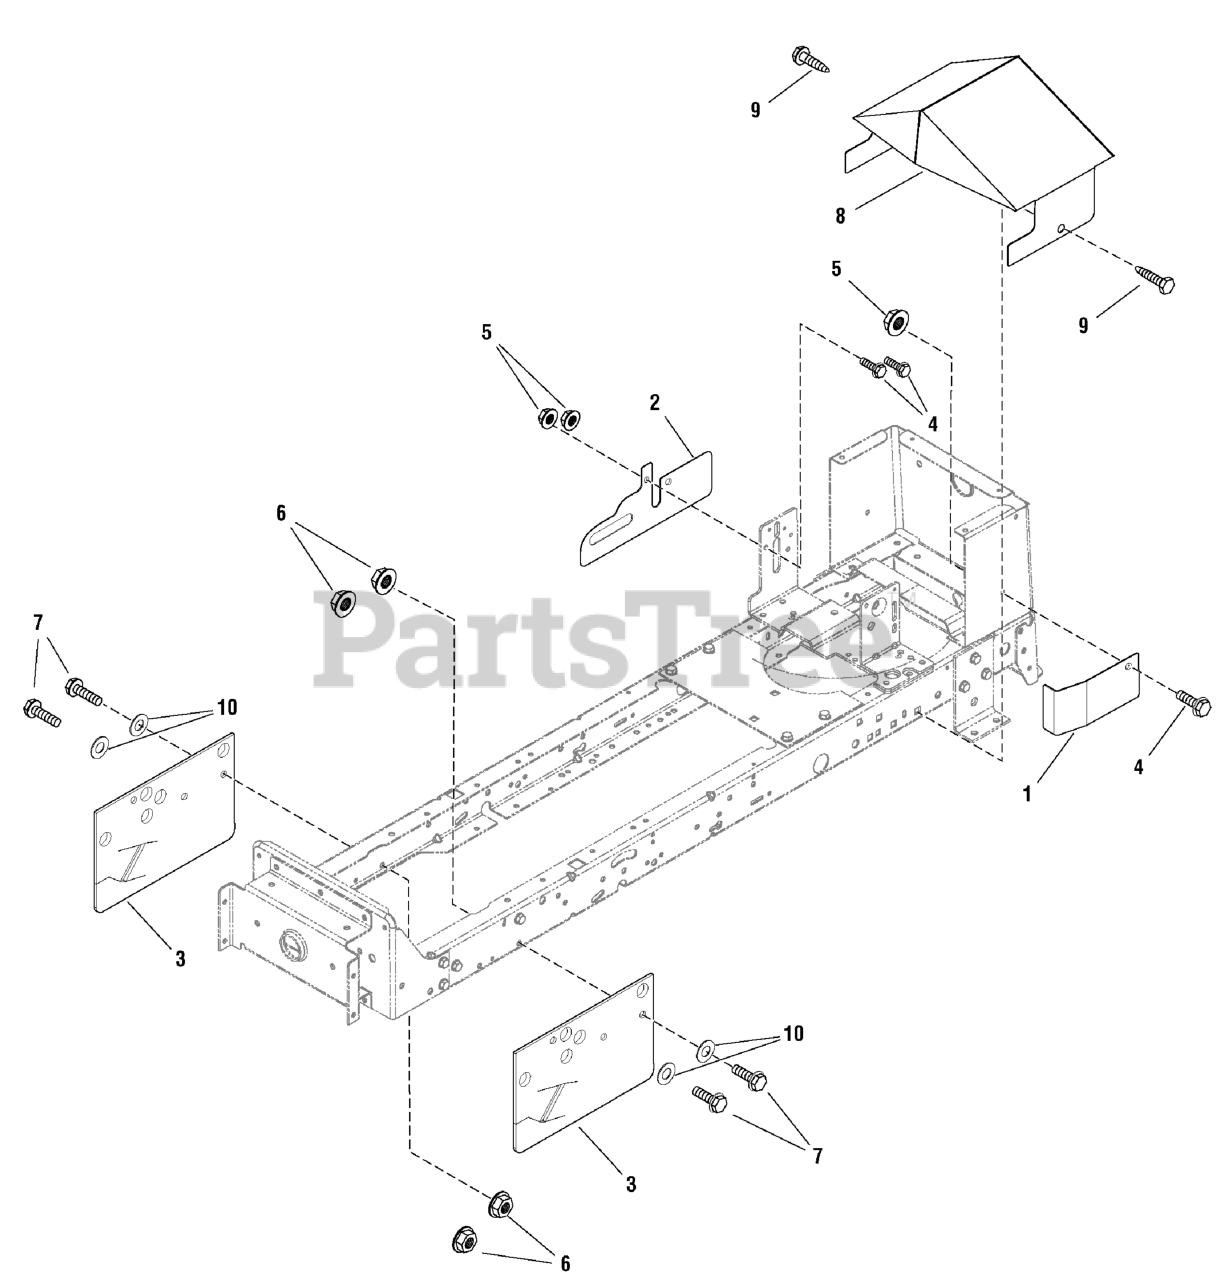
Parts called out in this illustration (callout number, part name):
1	PLATE, Rear Guard, Left
2	PLATE, Rear Guard, Right
3	GUARD, Rubber, Stack Pulley, Right
4	BOLT, Hex Flange, 1/4-20 x 3/4
5	NUT, Hex Flange, 1/4-20
6	NUT, Hex Flange Centerlock, 5/16-18
7	BOLT, Hex Head, 5/16-18 x 3/4
8	GUARD, Flat Fan
9	CAPSCREW, 5/16-18 x 3/4
10	WASHER, Flat, 3/8
